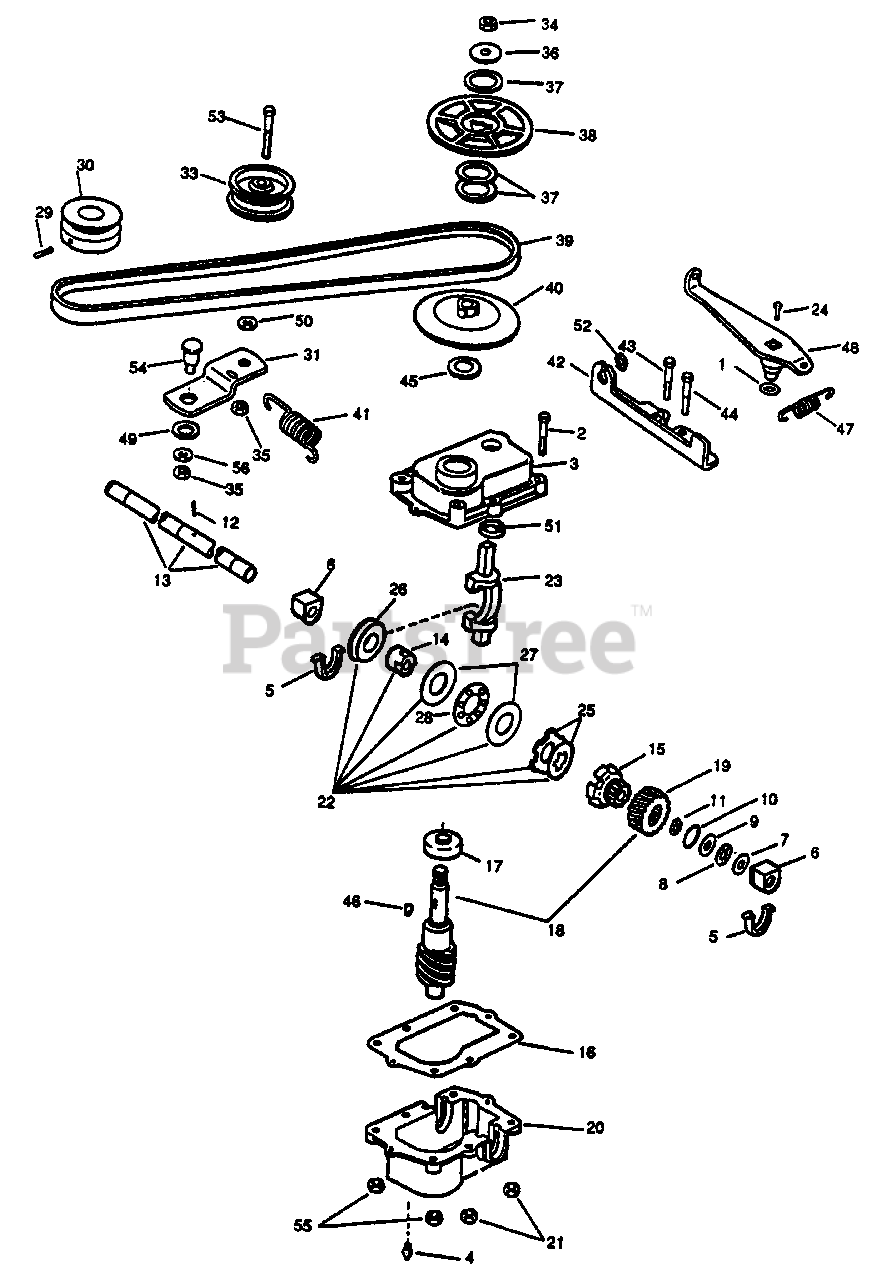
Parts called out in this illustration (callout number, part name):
1	O-Ring
2	Hex Hd. Cap Screw
3	Gearcase-Upper
4	Plug
5	Packing
6	Bearing & Seal-Gearcase
7	Thrust Washer
8	Thrust Bearing
9	Thrust Washer
10	Thrust Washer
11	Retaining Ring
12	Pin
13	Driveshaft
14	Driven Sleeve
15	Driver
16	Gasket
17	Bearing
18	Worm Wheel & Shaft Kit (Inc. 19)
19	Worm Wheel
20	Gearcase-Lower
21	Nut, Lock
22	Collar, Brg & Disc Kit (Inc. 23-28)
23	Shift Fork
24	Screw
25	Disc Plate Kit
26	Collar
27	Thrust Washer
28	Bearing
29	Set Screw
30	Pulley-Engine
31	Idler Arm
32	Screw
33	Pulley-Idler
34	Nut
35	Nut
36	Washer
37	Washer
38	Pulley-Upper Half
39	V-Belt
40	Pulley-Lower Half
41	Extension Spring
42	Conduit Anchor Bracket
43	Screw
44	Screw
45	Washer
46	Key
47	Extension Spring
48	Shift Arm & Hub Assembly
49	Washer
50	Washer
51	Seal Guide
52	Retaining Ring
53	Screw
54	Shoulder Bolt
55	Nut, Lock
56	Washer
